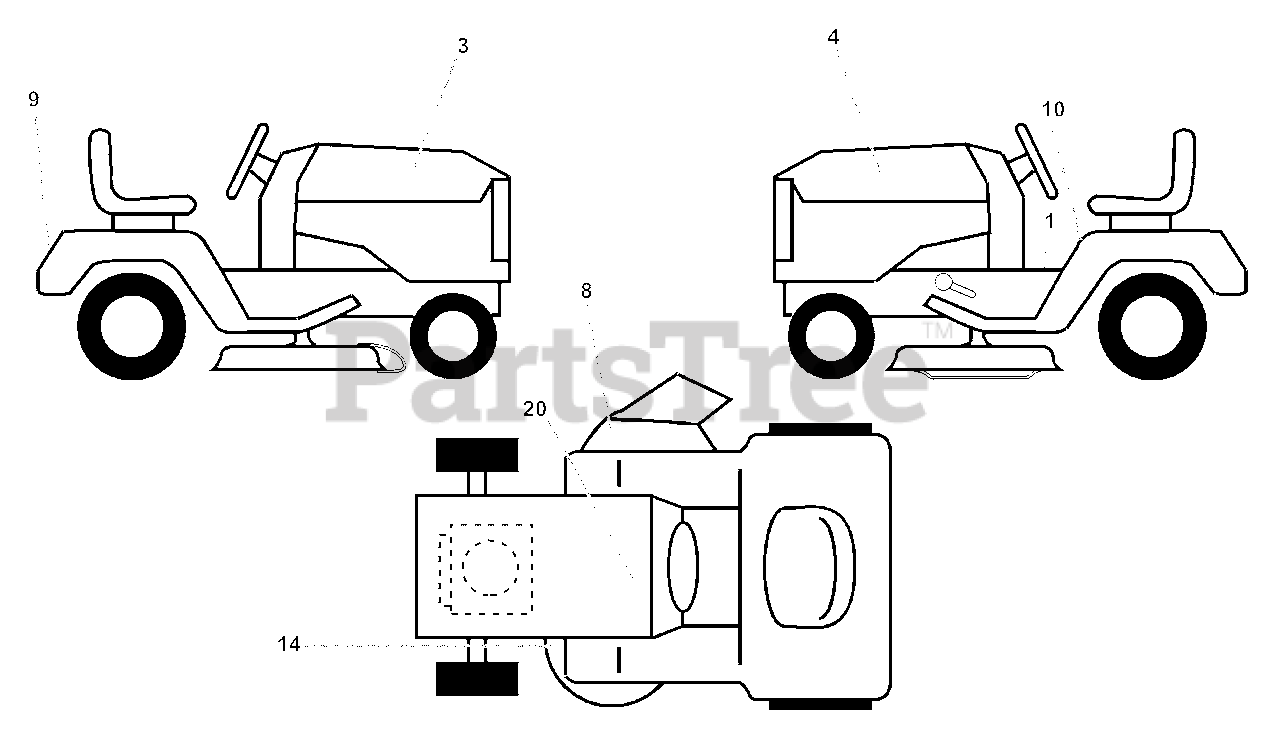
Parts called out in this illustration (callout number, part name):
1	Decal Fend Stlt Oper Inst E/F
3	Decal Hood LH
4	Decal Hood RH
8	Decal Warning Multi-Lang
9	Decal Fender Husq
10	Decal Fender Danger E/F
14	Decal V-Belt Schematic
20	Decal Bat Dan/Psn
